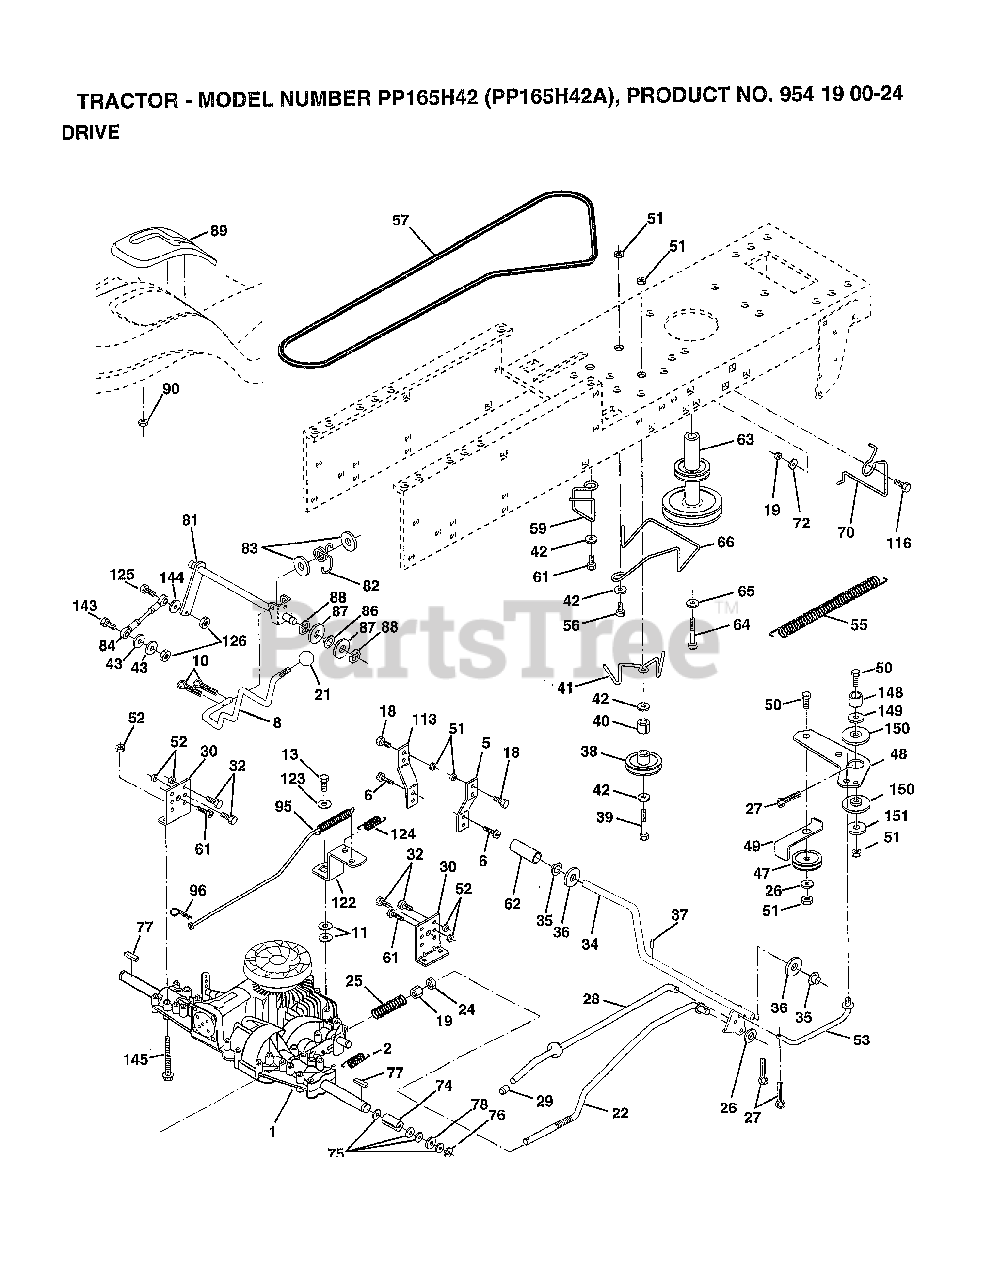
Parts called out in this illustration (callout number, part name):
2	SPRING.BRAKE.RETU
5	STRAP TORQUE
6	SCREW
8	"ROD SHIFT,FENDER"
10	PIN COTTER 1/8
11	WASH-SHFT PLT LT
13	BOLT.1/4-28.W/PAT
18	BOLT
19	NUT
21	KNOB.DUCKHEAD.1/2
22	BRAKE ROD
24	NUT
25	SPRING ROD LT
26	WASHER
27	COTTER PIN
28	ROD.BRAKE.PARK.LT
29	PLUNGER CAP T
30	TRANSAXLE MTG BKT
32	BOLT
34	SHAFT ASM-PEDAL F
35	NYLON BEARING
36	WASHER LT
38	PULLEY.IDLER.FLAT
39	BOLT
40	SPACER T
42	WASHER
43	WASHER T
48	BELLCRANK.CLUTCH
49	RETAIN BELT
53	"LINK, CLUTCH T"
55	"SPRING, RETURN LT"
57	"V-BELT,GROUND DRV"
59	KEEPER BELT CNTSP
61	SCREW
62	PEDAL COVER T
63	PULLEY.ENGINE
64	BOLT
65	LOCKWASHER
66	KEEPER-BELT
70	KEEPER BELT ENG
72	WASHER
74	"SPACER AXLE,PVST"
76	E-RING LT
77	SQUARE KEY
78	WASHER
81	SHAFT ASSEMBLY
82	"SPRING,TORSION"
83	WASHER
84	ROD TIE
86	BUSHING
87	WASHER D
88	KLIP RING
90	NUT
95	ROAD ASM BYPASS
113	"STRAP,TORQUE"
116	BOLT RDHD 3/8-16
122	"PLATE-BYPASS,PVST"
123	WASHER
124	SPRING RETURN
143	BOLT
144	WASHER
145	BOLT.HEX.FLGHD
149	SPACER RETAINER
150	BUSHING.NYLON
151	WASHER
